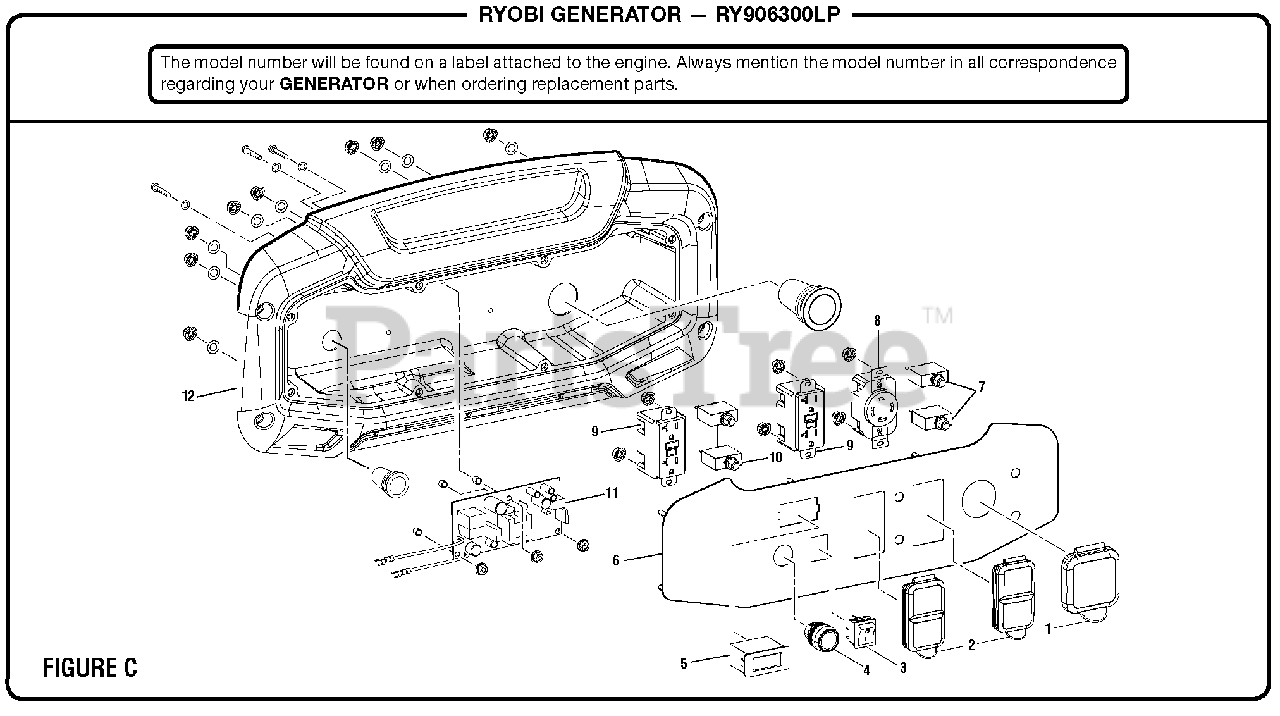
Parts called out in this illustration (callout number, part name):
1	240 Volt ReceptacleRain Cover
2	120 Volt Receptacle Rain Cover
3	Engine Stop Switch
4	Engine Start Switch
5	Digital Meter
6	Front Panel (Faceplate)
7	Circuit Breaker (27 Amp)
8	Twist Lock Recepticle (120/240 Volt, 30 Amp, L14-30)
9	Duplex Receptacle (120V)
10	Circuit Breaker (20 Amp)
11	Battery Charger
12	Control Box (Back Panel)
